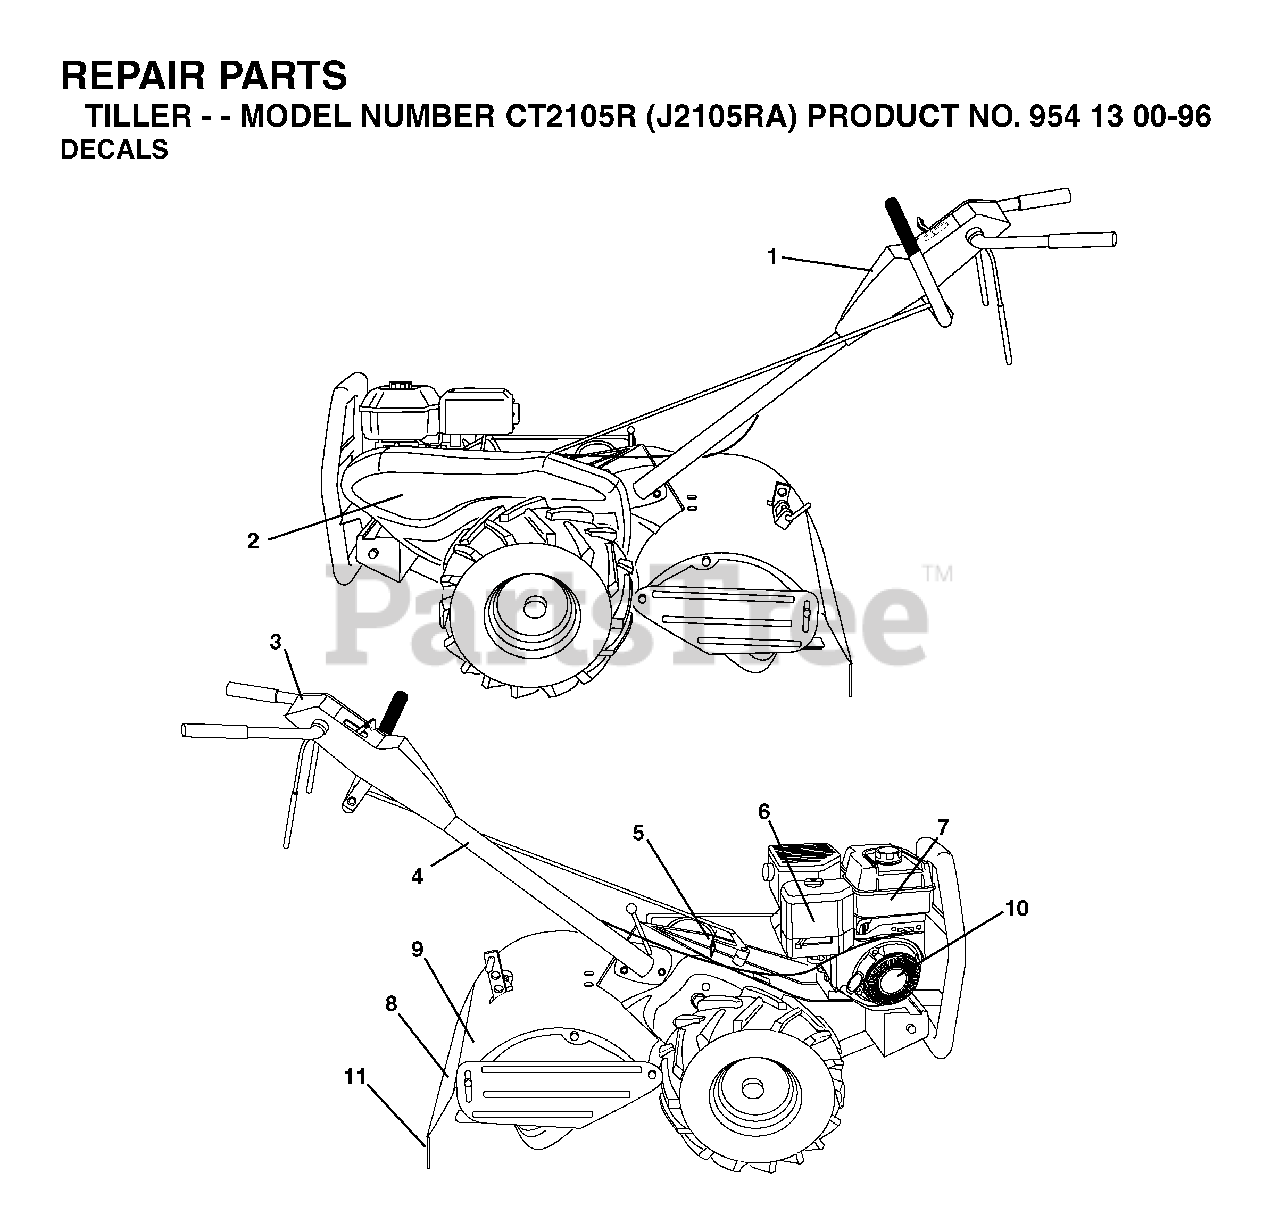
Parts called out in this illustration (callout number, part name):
5	DECAL.SHIFT.INDICATOR.TILLER
9	DECAL EUROPE STANDARD CE
10	DECAL.REWIND
